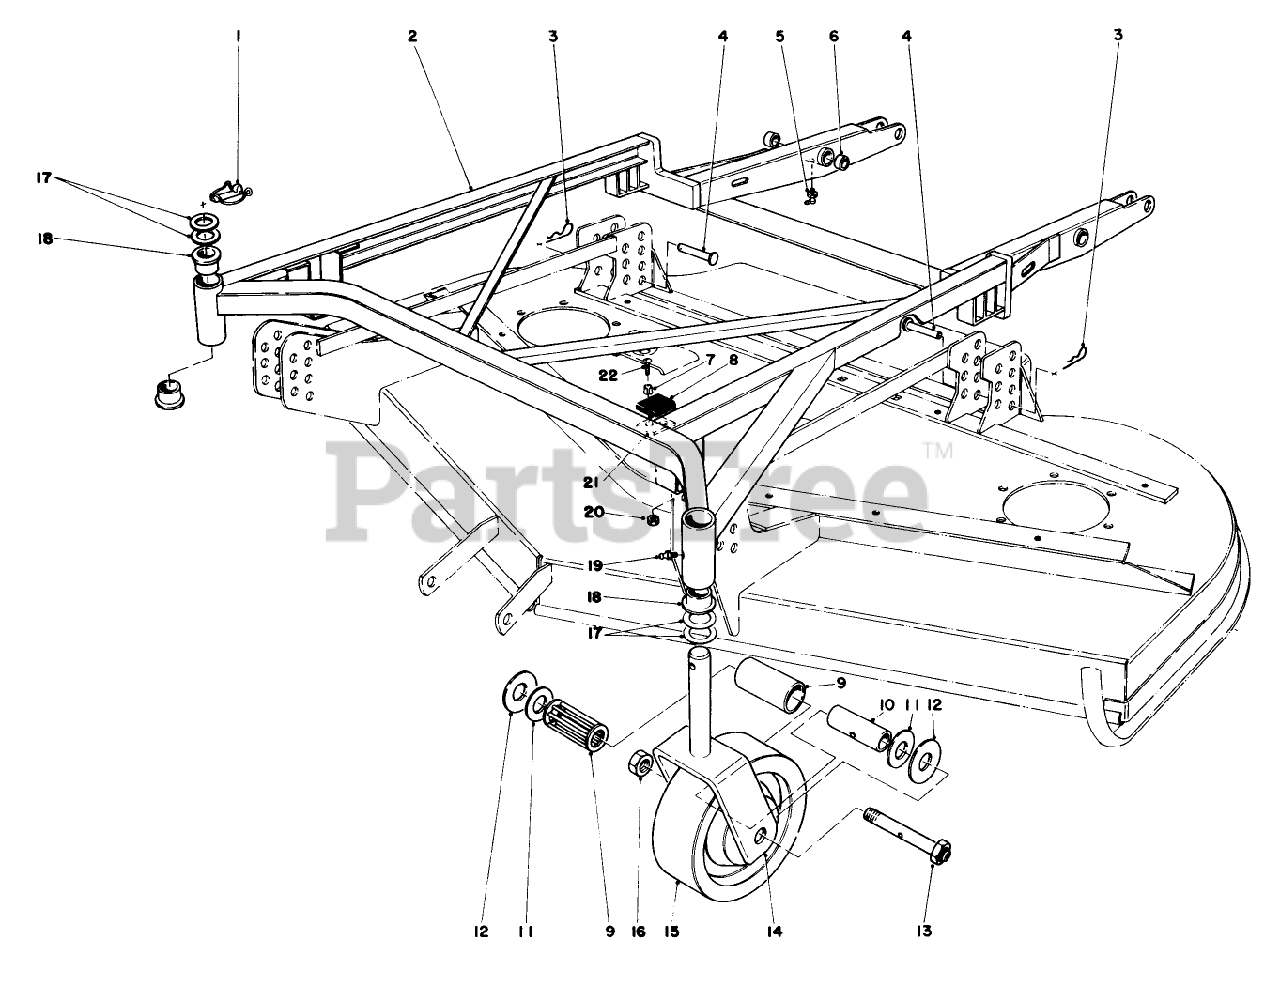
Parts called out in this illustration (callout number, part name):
1	PIN-LYNCH
2	Frame-Deck Assembly (Incl. Ref. #5, 6 & 18)
3	PIN-HAIR
4	PIN-CLEVIS
5	FITTING-GREASE, 90 DEG
6	7/8 ID X 1.128 X 7/8 LG BSHG
7	SPACER
8	CUSHION-RUBBER
9	ROLLER BEARING
10	BUSHING
11	BEARING RETAINER
12	THRUST WASHER
13	SCREW-HH
14	FORK-Castor
15	Wheel Assembly (Incl. Ref. #9-12)
16	NUT-LOCK
17	WASHER-THRUST
18	Bushing
19	FITTING-GREASE
20	NUT-LOCK, NI
21	SHIM-CUSHION
